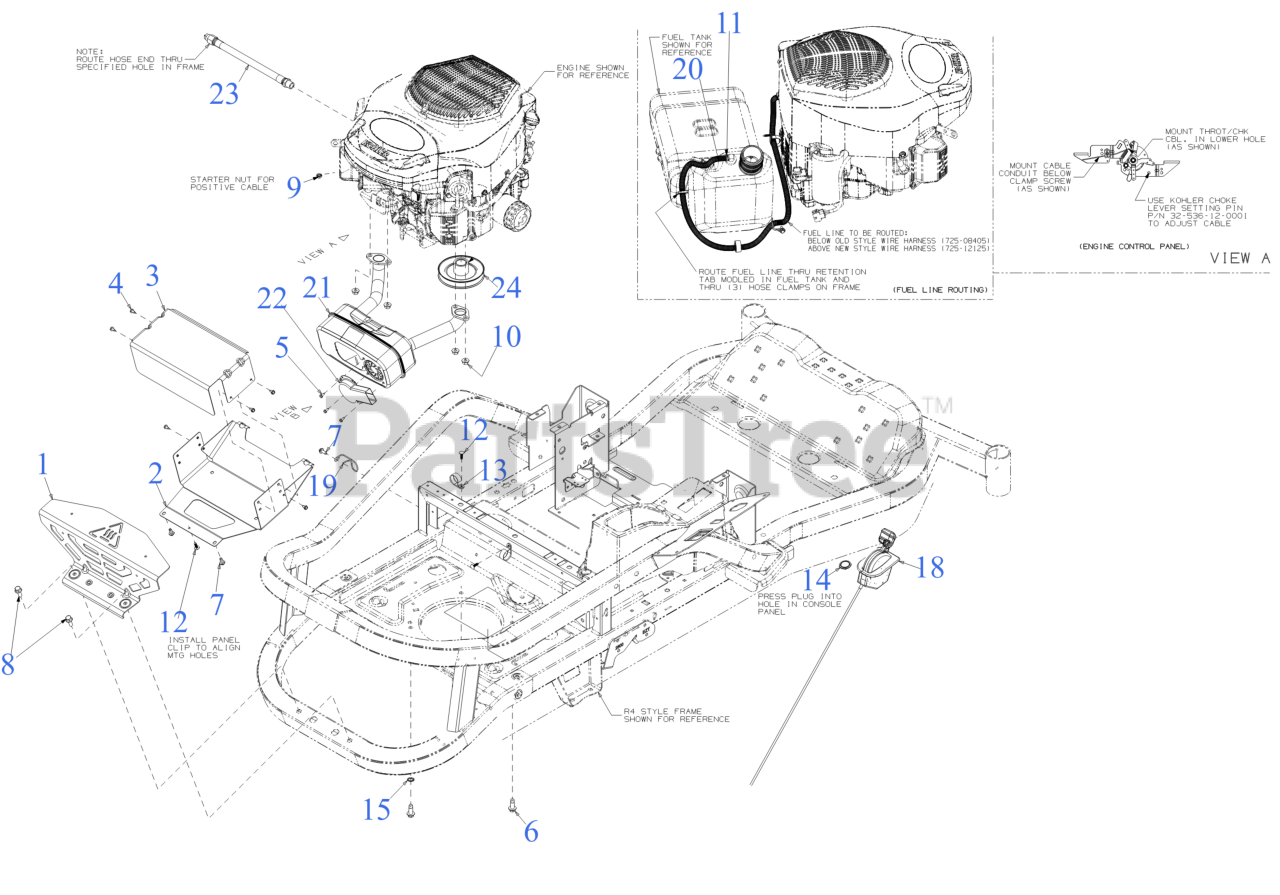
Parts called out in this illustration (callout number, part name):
1	MUFFLER COVER (REAR) (BLACK)
2	MUFFLER SHIELD (LOWER)
3	MUFFLER SHIELD (TOP)
4	HEX SCREW AB-TAP #10 x .50
5	HEX SCREW WASHER HD #8-18 x 0.500
6	SCREW 3/8-16 x 1
7	SCREW M6-1 x .625
8	SCREW 5/16-18 x .875 GR5 HXFLG HD
9	HEX NUT 1/4-20
10	HEX FLANGE NUT M8X
11	HOSE CLAMP 1/20
12	RATCHET CLIP (.188 x .85)
13	DRAIN HOSE CLAMP
14	CHOKE PLUG
15	LOCK WASHER 3/8
18	THROTTLE CABLE 51.0LG
19	HOSE GUIDE
20	FUEL HOSE LOW PERMEATION 45"
21	EXHAUST MUFFLER (KH TWIN)
22	EXHAUST DELECTOR (LONG)
23	OIL DRAIN HOSE (11.26" 3/8 NPT)
24	TRANSMISSION DRIVE PULLEY
